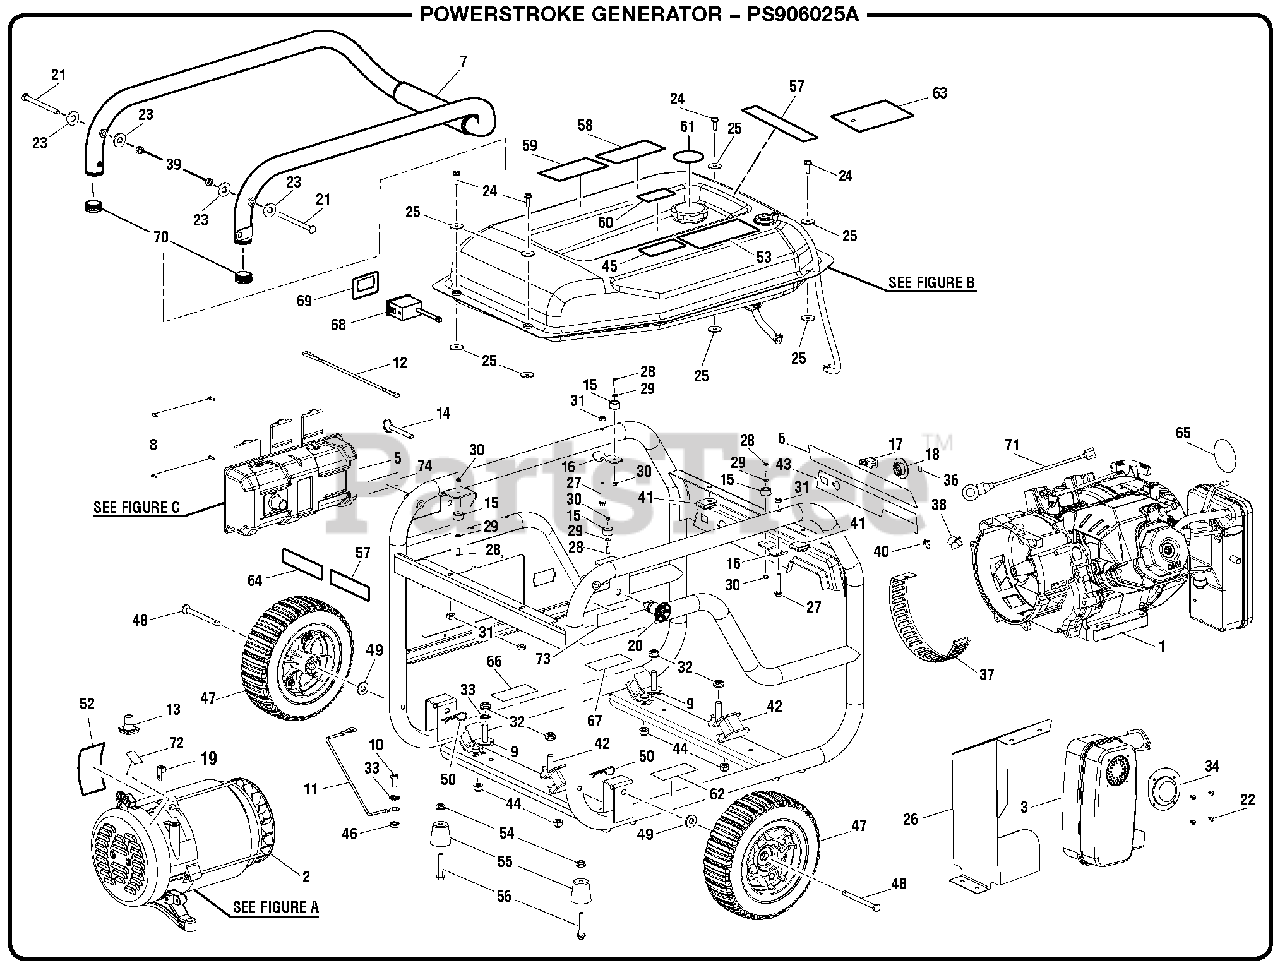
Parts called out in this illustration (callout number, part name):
1	Engine (Rato 390cc)
2	Generator Head Assembly (See Fig. A)
4	Frame Assembly
5	Control Panel Assembly (See Fig. C)
6	Logo Label
7	Handle Assembly
8	Screw (6-20 x 3/8 in.)
9	Engine Isolator (Right)
10	Bolt (5/16-18 x 3/4 in.)
11	Ground Wire Assembly
13	Rubber Sleeve
14	Release Pin
15	Handle Bumper
16	Handle Support Bracket
17	On/Off Switch
18	Fuel Valve Bezel
19	Ground Lug
20	Handle Release Pin
21	Pivot Pin (Handle)
22	Screw (8-32 x 3/8 in.)
23	Washer (5/16 in.)
24	Bolt (M6 x 25 mm, Flange Hex Hd.)
25	Washer (1/4 in.)
26	Heat Shield
27	Bolt (M6 x 45 mm)
28	Bolt (M4 x 12.5 mm, Hex Hd.)
29	Washer (M4)
30	Flange Nut (M4)
31	Lock Nut (M6)
32	Lock Nut (M10)
33	Star Washer (5/16 in.)
34	Spark Arrestor
35	Lock Nut (1/2-20)
36	Fuel Label
37	Fan Cover (Generator Head)
38	Plug (Generator Head)
39	Hex Nut (M8)
40	Bolt (M5 x 10 mm, Flange Hex Hd.)
41	U-Clip (M6)
42	Engine Isolator (Left)
43	Start Label
44	Flange Nut (M8)
45	Fuel Stabilizer Label (Spanish)
46	Hex Nut (5/16-18)
49	Washer (M10)
50	Hitch Pin
51	Hot Surface Label
52	Lock and Pin Label
53	Danger Label
54	Lock Nut (M8)
55	Foot Assembly
56	Bolt (M8 x 45 mm, Flange Hex Hd.)
57	Fire Distance Label (Eng/Sp)
58	CPSC Label
59	Fire Danger Label
60	E85 Label
61	Fuel Stabilizer Label
62	Combustion Label (Eng/Sp)
63	Warning Hangtag
64	Ground Warning Label
65	Recoil Housing Label
66	Lubricant Label
67	Inquires label
68	Analog Hour Meter
69	Systems Monitor Label
70	End Cap (31 mm)
71	Wire Assembly (Green)
72	Ground Label
73	Handle Release Label
